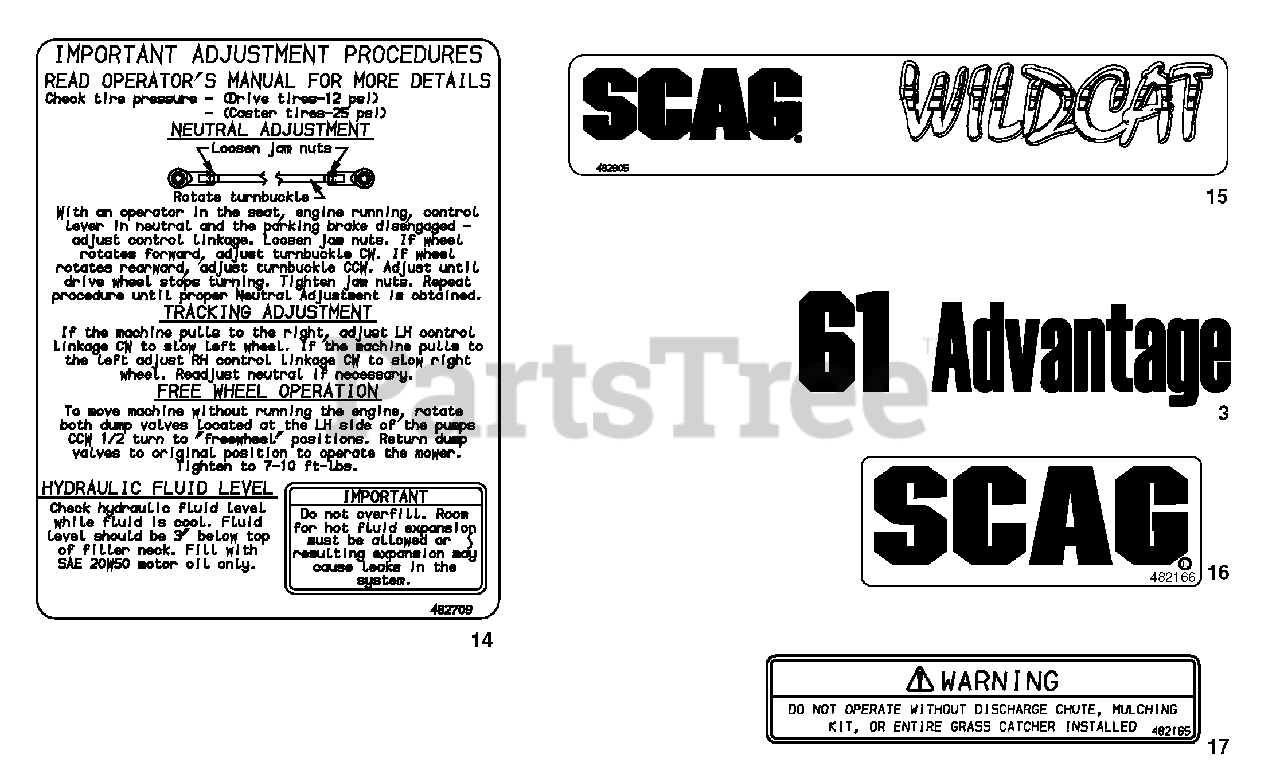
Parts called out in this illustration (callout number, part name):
3	Decal, 61A
14	Decal, Seat Support
15	Decal, Rear Bumper
16	Decal, Front Footplate
17	Decal, Discharge Chute
